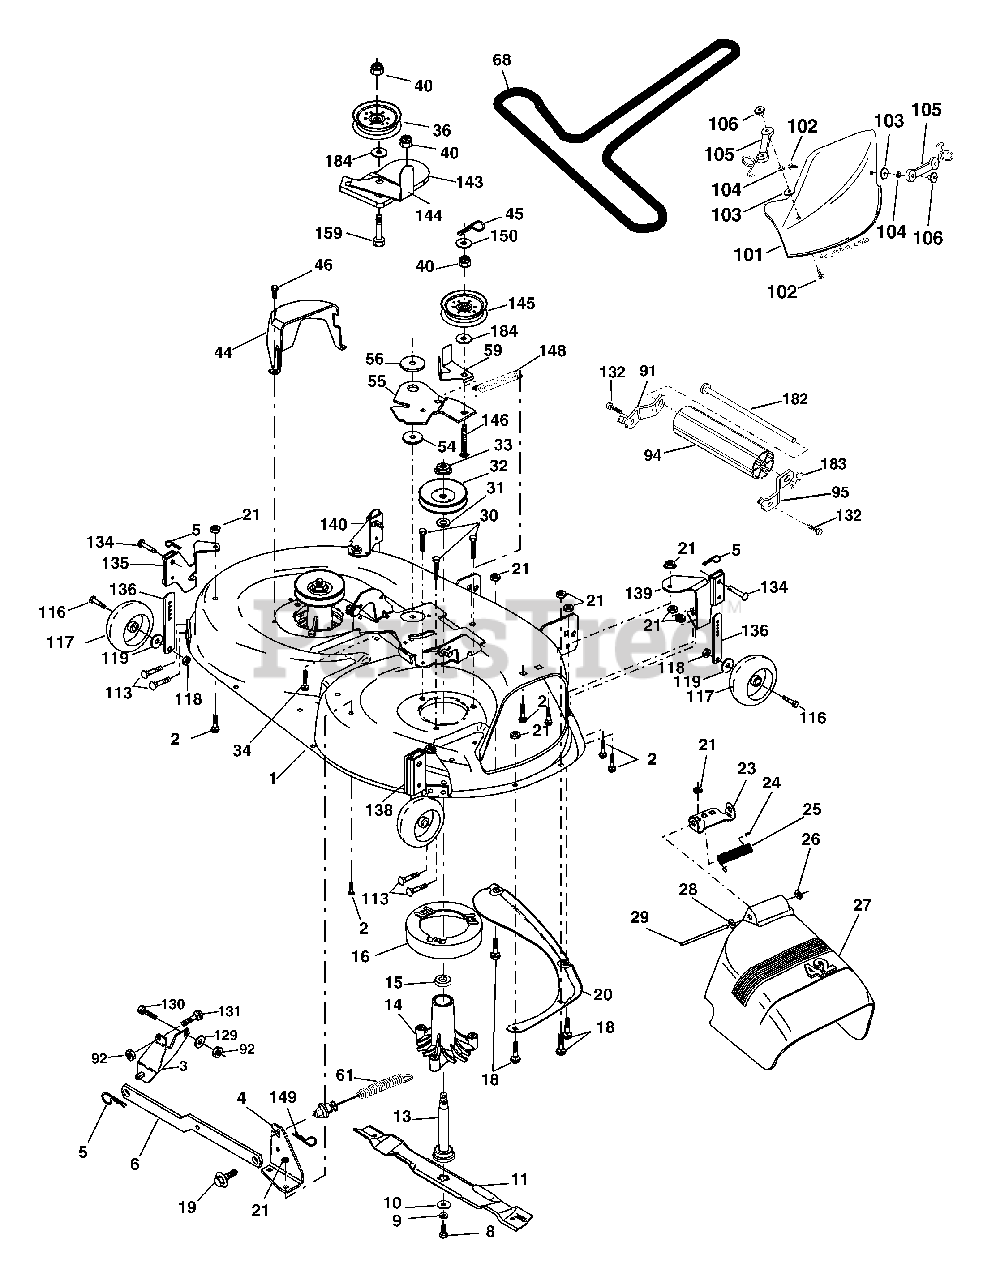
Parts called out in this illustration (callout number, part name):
1	Mower Deck Assembly, 42"
2	Bolt
3	Bracket Assembly,Sway Bar, Front
4	Bracket Sway Bar 42" Deck
5	Retainer Spring
6	Bar Sway Deck
8	Bolt, Hex 3/8-24 x 1.25 Gr. 8
9	Washer, Lock
10	Washer, Hardened
11	Blade Mulching STD
11	Blade Mulching Premium
11	Blade Hi-lift
13	Shaft Assembly, Mandrel, Vented
14	Housing, Mandrel, Vented
15	Bearing, Ball, Mandrel
16	Stripper
18	Bolt, Carriage 5/16-18 x 5/8
19	Bolt, Shoulder
20	Baffle, Vortex
21	Nut Crownlock 5/16-18 unc
23	Bracket, Deflector
24	Cap, Sleeve
25	Spring, Torsion, Deflector
27	Shield, Deflector
28	Washer 11/32 x 5/8 x 16 Ga.
29	Rod, Hinge
30	Screw Thdrol Hex
31	Washer, Spacer
32	Pulley, Mandrel
33	Nut, Toplock, Flanged
34	Bolt Carr. Sh 3/8-16 x 1-1/2 Gr. 5
36	Pulley, Idler, Flat
40	Nut Lock Flg 3/8-16 unc
44	Guard, Mandrel, L.H.
45	Retainer
46	Screw, Thd. Roll 1/4-20 x 5/8
54	Washer, Hardened
55	Arm, Idler
56	Spacer, Retainer
59	Guard, TUV Idler
61	Spring Ext Elect Clutch 42" Dck
91	Bracket Asm Noseroller Lh
92	Nut Lock Hex w/Ins. 3/8
94	Roller Nose 38"-50"
95	Bracket Asm Noseroller Rh
101	Cover Mulching
102	Screw Pan Hd Phillips 10-24 x 5/8
103	Washer #10
104	Washer Lock #10
105	Latch Asm.
106	Nut Weld
113	Screw 5/16-18 x 3/4 Tap R
116	Bolt, Shoulder
117	Wheel, Gauge
118	Nut, Centerlock 3/8-16
119	Washer 3/8 x 7/8 x 14 Ga.
129	Washer 13/32 x 13/16 x Ga.
130	Bolt Fin Hex 3/8-16 unc x 1 Gr. 5
131	Bolt Rdhd Sqnk 3/8-16 unc x 1
132	Screw 3/8-16 x .75
134	Pin Head Rivet
135	Bracket Asm Whl GA R LH
136	Bar Adjusting GA WHL
138	Bracket Asm Whl GA R RH
139	Bracket Asm Whl GA F RH
140	Bracket Asm Whl GA F LH
143	Bracket Arm Idler 42"
144	Keeper Belt 42" Clutch Cable
145	Pulley Idler Flat
146	Bolt Carriage Idler
148	Spring Return Idler
149	Retainer Spring Yellow Zinc
150	Washer 9/32 x 3/4 x 10 Ga.
159	Bolt Rdhd Sqn 3/8-16 unc x 1- 3/4
182	Rod Roller Nose
183	Retainer Spring
184	Washer 13/32 x 7/8 x 10 Ga.
